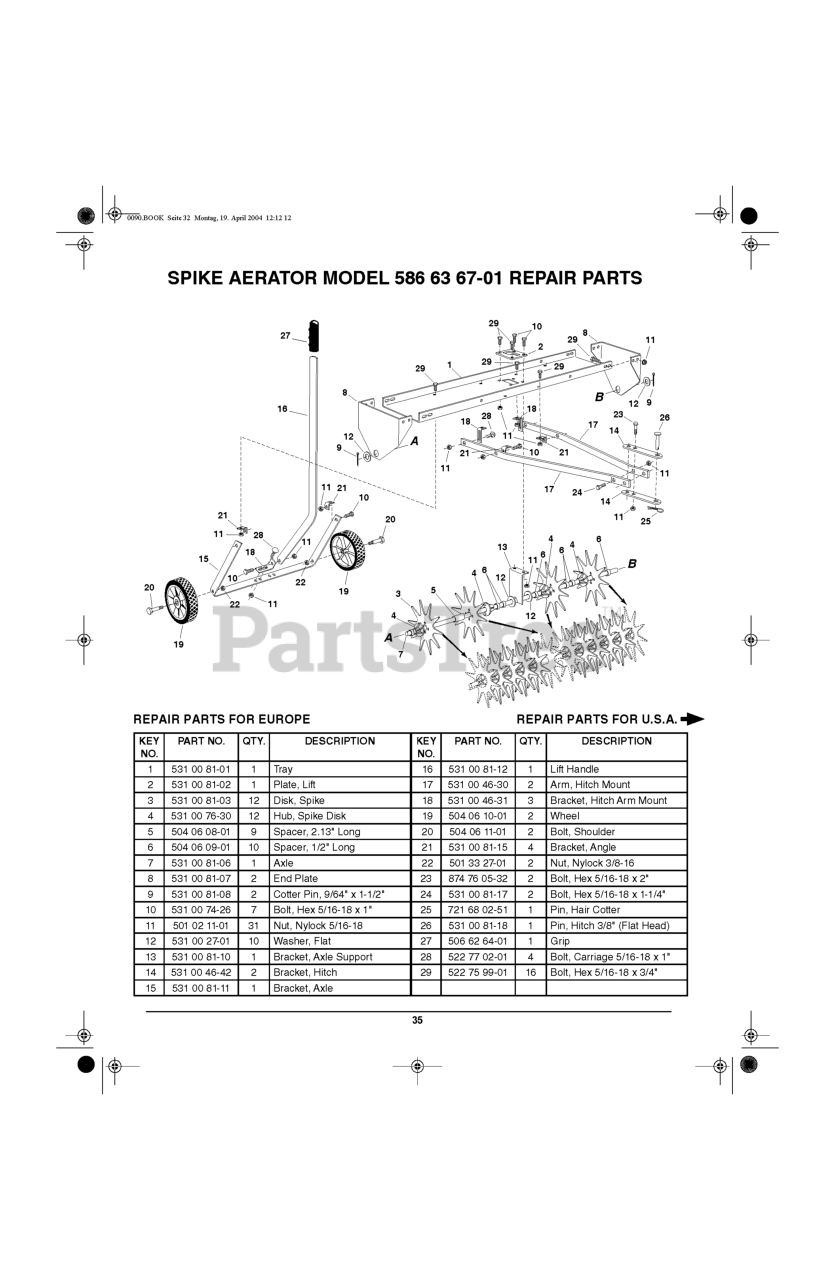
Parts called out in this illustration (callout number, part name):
14	BRACKET THATCHER
23	Bolt Fin Hex 5/16 - 18 Unc x 2 Gr. 2
27	Rubber Grip
